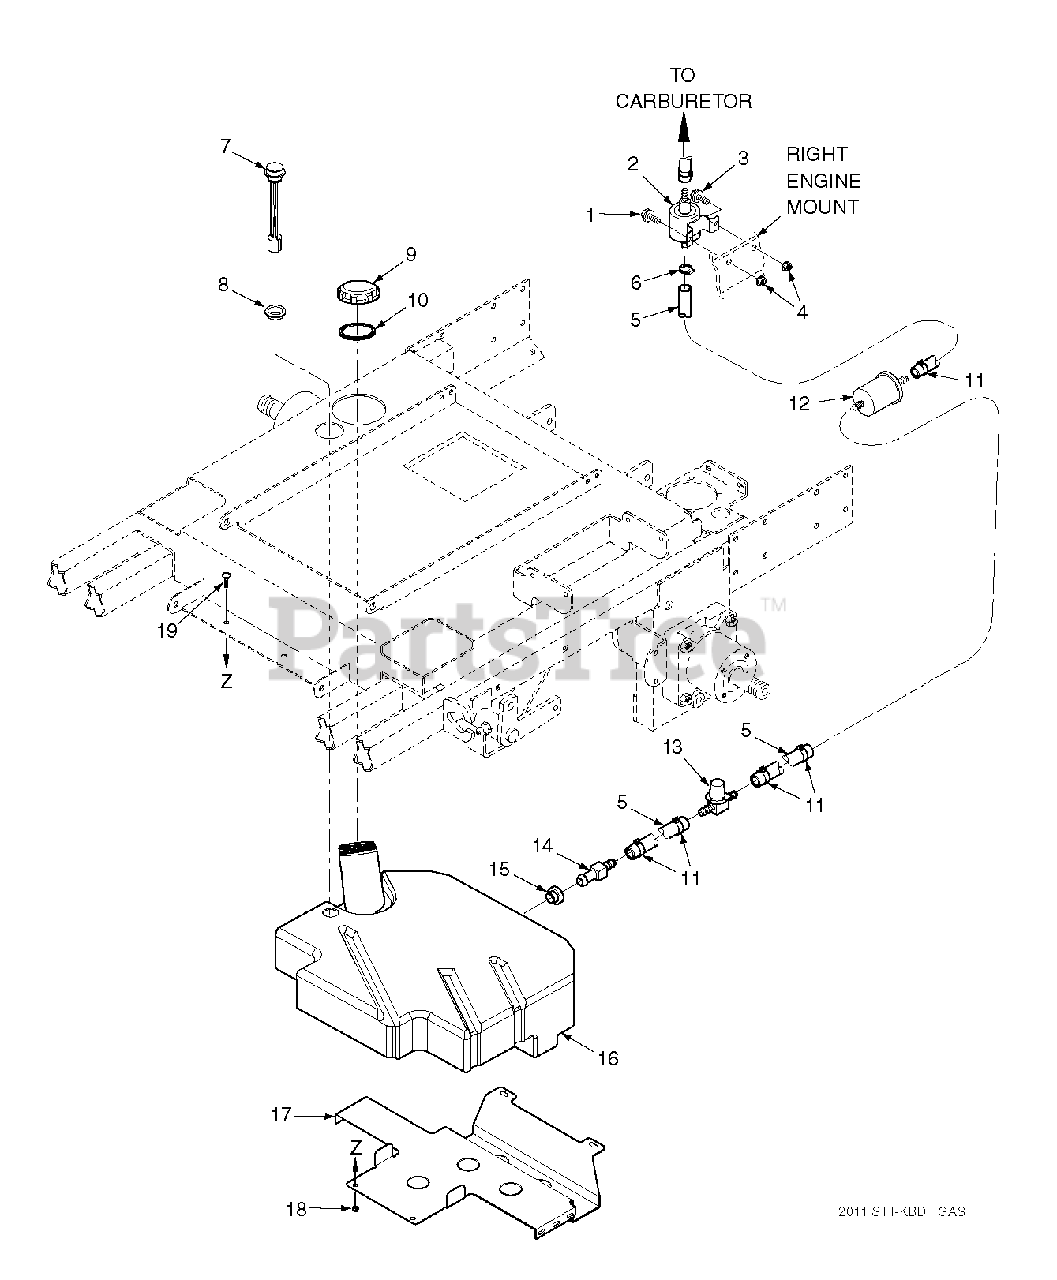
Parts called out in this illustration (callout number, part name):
1	Bolt, Hex Hd. 1/4-20 x 3/4"
2	Fuel Pump, Kubota
3	Bolt, Hex Hd. 1/4-20 x 1"
4	Nut, Hex, Elastic Stop 1/4-20
5	Fuel Hose, 5/16" ID. Non-Perm.
6	Hose Clamp, 0.69" dia.
7	Fuel Gauge Assy.
8	Seal, Fuel Gauge
9	Cap, Fuel Tank
10	Gasket, Fuel Cap
11	Clamp, 5/16" Fuel Hose
12	Fuel Filter, Kubota
13	Valve, Shutoff
14	Hose Fitting
15	Bushing
16	Fuel Tank Assembly
17	Support Bracket, Fuel Tank
18	Nut, 5/16-18 Serr. Flng.
19	Bolt, Carriage 5/16-18 x 3/4"
